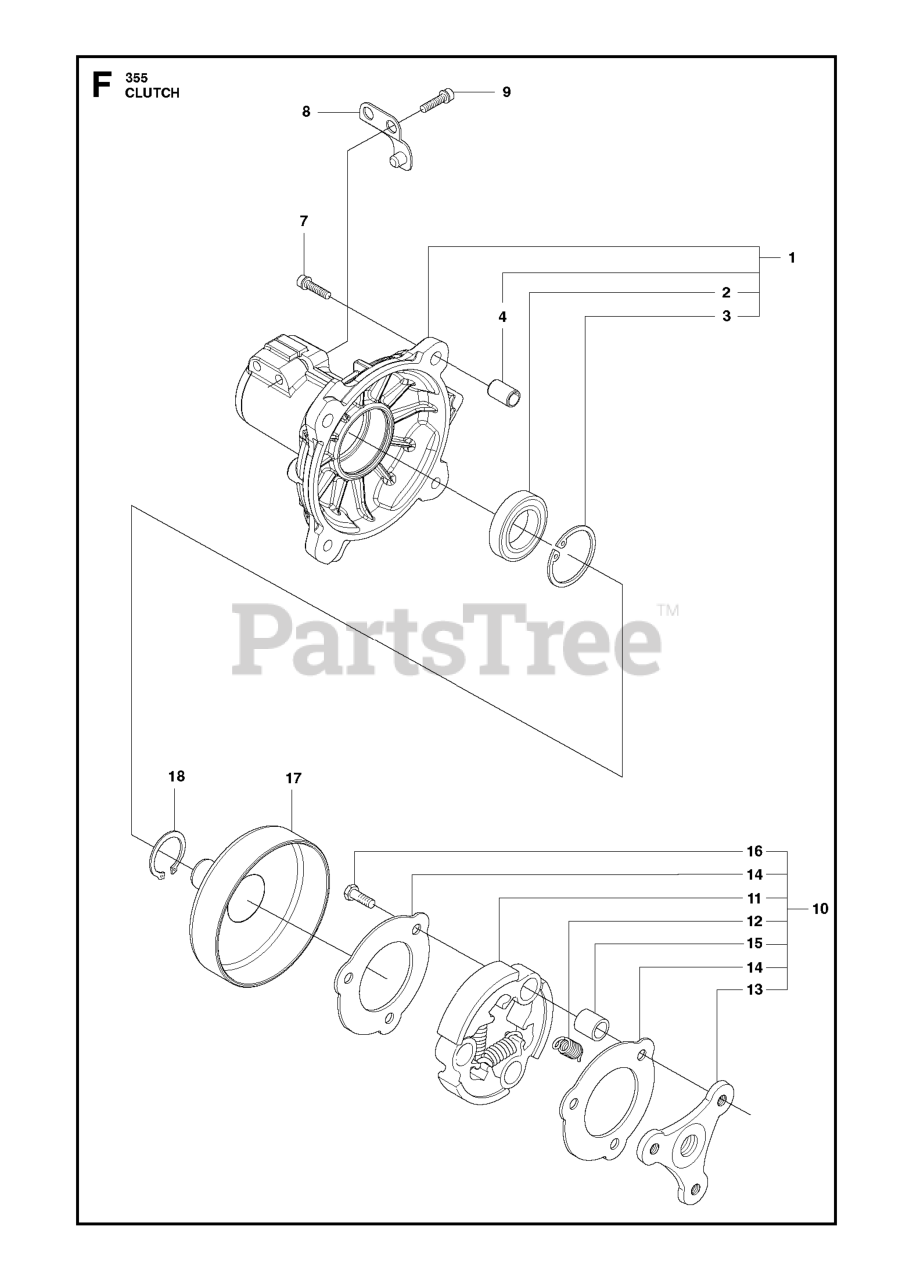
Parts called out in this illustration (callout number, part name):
1	Covers
2	BALL BEARING 6202-2RS1
3	RETAINING RING SGH 35
4	Sleeves
4	GUIDE BUSHING
8	LOCKING PLATE
10	CLUTCH ASSY
11	CLUTCH SHOE
12	CLUTCH SPRING
13	CLUTCH HUB
17	CLUTCH DRUM ASSY
18	RETAINING RING SGA 15
